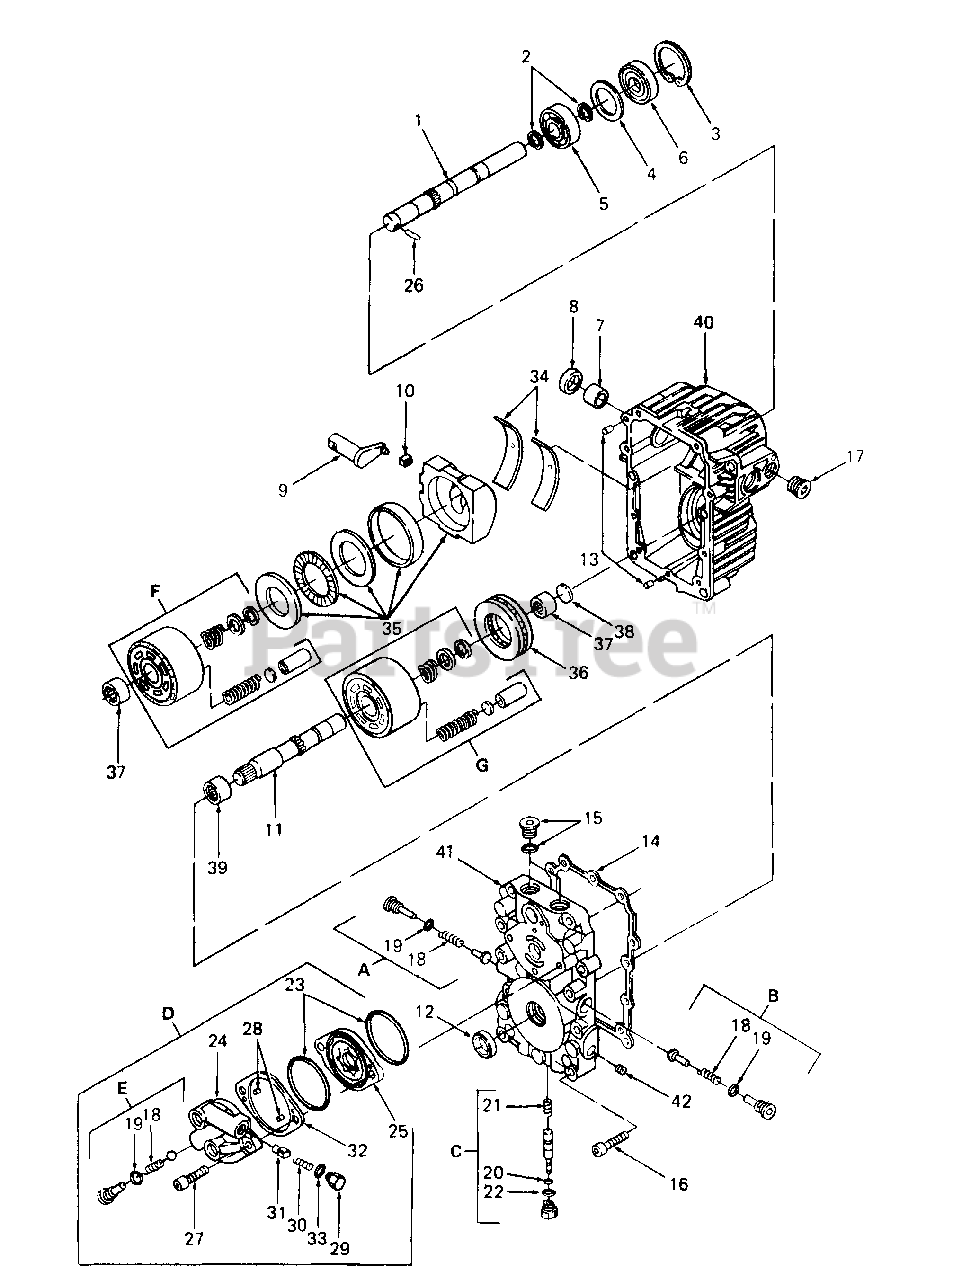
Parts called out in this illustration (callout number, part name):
1	Shaft
2	Ring, Retaining
3	Ring, Retaining
4	Spacer
5	Bearing, Ball
6	Seal, Lip
7	Bearing, Journal
8	Seal, Lip
9	Arm, Trunnion
10	Guide, Slot
11	Shaft, Motor
12	Not used in this application
14	Gasket, Center Section
19	O-Ring
20	O-Ring
21	Spring
22	O-Ring
23	O-Ring
24	Housing, Charge Pump
25	Gerotor Assy
29	Plug
31	Cone, Relief Valve
32	Shim, Charge Pump
34	Bearing, Cradle
35	Swashplate Assy
36	Bearing, Ball Thrust
37	Bearing, Needle
38	Washer, Thrust
39	Bearing, Needle
40	Housing Assy
41	Center Section Assy
A	Kit, Poppet Check Valve,
B	Kit, Orificed Check Valve,
C	Kit, Bypass Valve
D	Kit, Charge Pump
E	Kit, Check Valve
F	Kit, Pump Cylinder Block
G	Kit, Motor Cylinder Block
